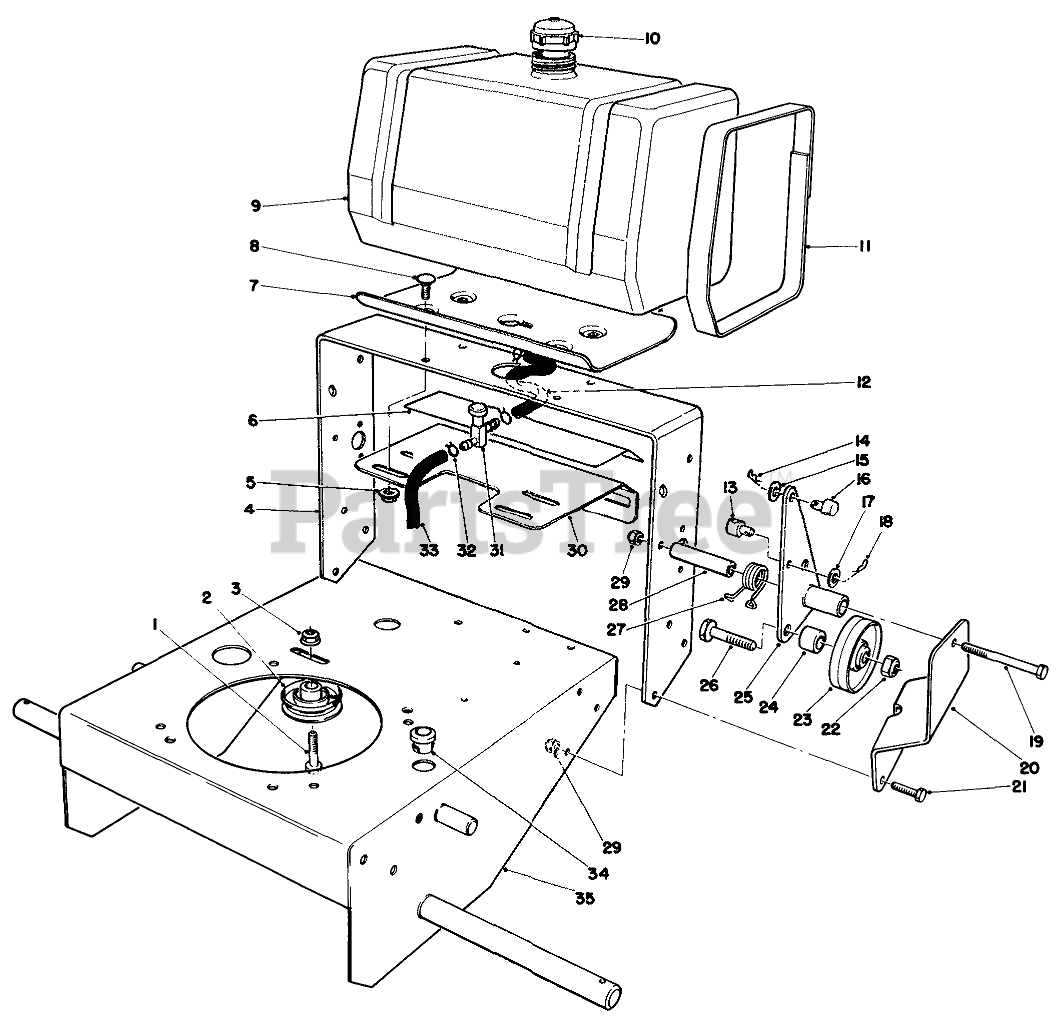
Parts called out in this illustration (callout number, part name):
1	SCREW-HH
2	PULLEY-IDLER
3	NUT-HF
4	Frame-Rear
5	NUT-HF
6	Decal-Ground Speed
7	Plate-Fuel Tank
8	BOLT-CARR
9	Tank-Fuel
10	GAS CAP
11	Hinge-Seat
12	Hose-Gas
13	ROD FITTING
14	PIN-COTTER
15	WASHER-PLAIN
16	ROD FITTING
17	WASHER-PLAIN
18	PIN-COTTER
19	SCREW-HH
20	Support-Idler L.H.
21	SCREW-HH
22	NUT-LOCK, NI
23	IdlerWheel
24	WHEEL IDLER SPACER
25	LH IDLER BRKT WA
26	SCREW-LEVELER
27	SPRING-TORSION, LH
28	PIVOT-IDLER SPACER
29	NUT-LOCK, NI
30	CONTROL PLATE R
31	FUEL VALVE
32	Clamp
33	HOSE-FUEL
34	BUSHING
35	Frame
